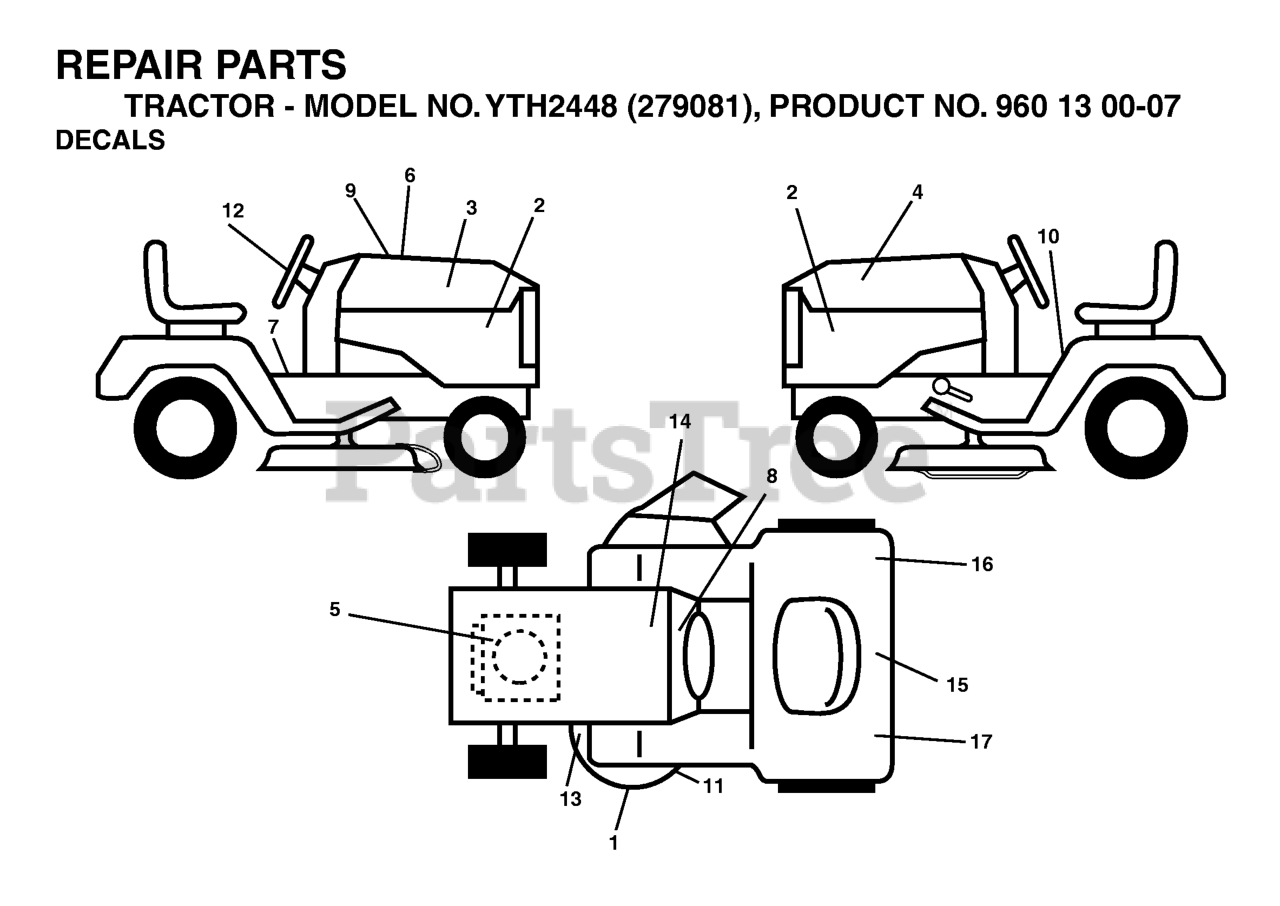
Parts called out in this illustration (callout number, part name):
2	DECAL, PANEL YTH2448
5	DECAL.ENG.BS.24HP
6	DECAL HOOD CUST. RESP.
11	DECAL V-BELT SCHEMATIC
12	DECAL.STEERING.HUSQ.BLUE
13	DECAL.MOWER
14	DECAL BTRY SYMBOLS
15	DECAL.FENDER
